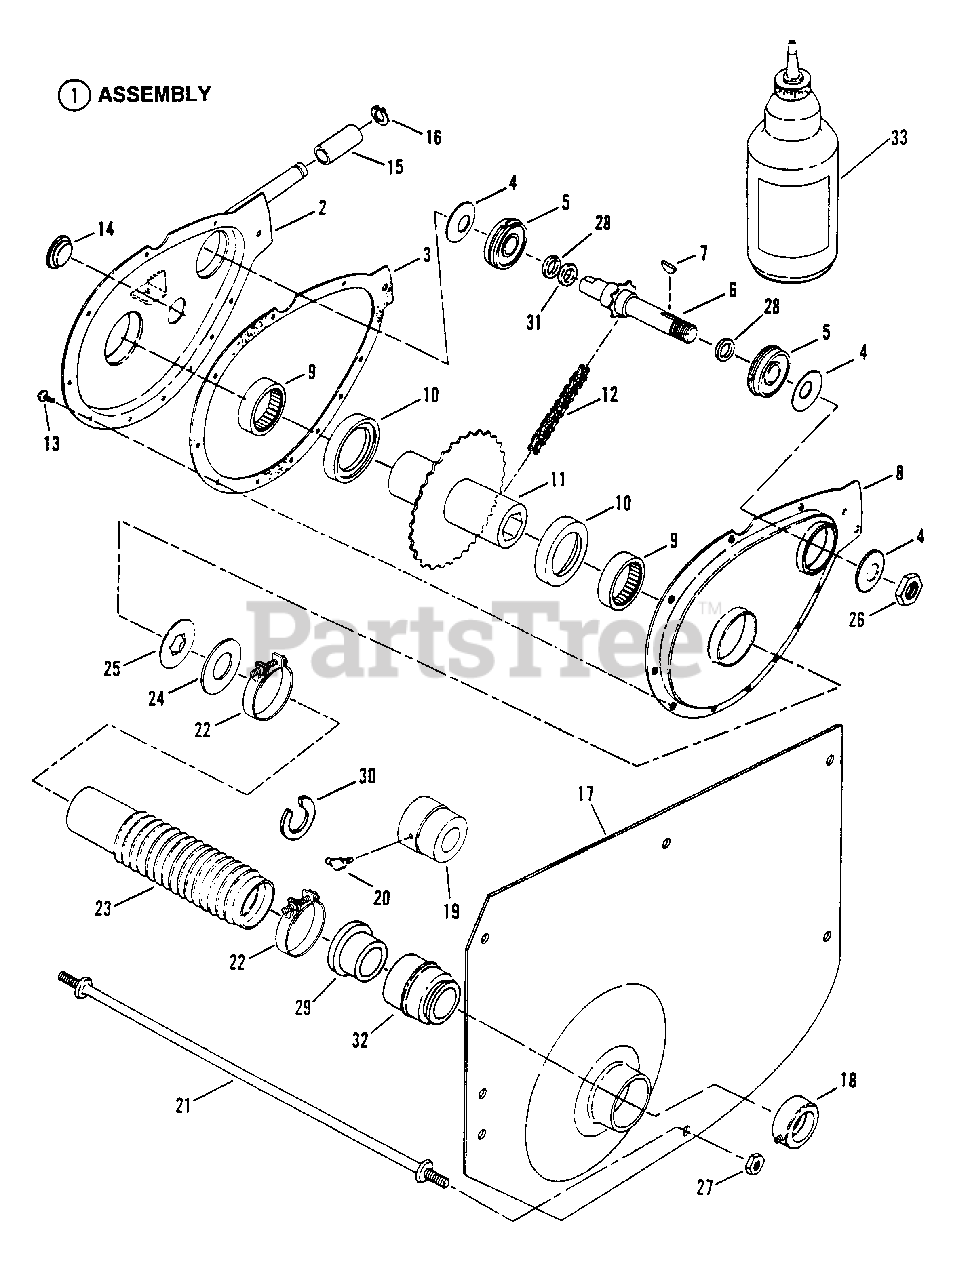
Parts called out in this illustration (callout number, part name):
1	ASSEMBLY, Chain Case
2	CASE, Sprocket
3	GASKET, Case Cover
4	WASHER, Belleville
5	BEARING, Ball
6	SPROCKET & SHAFT
7	KEY, 1/8 x 5/8" Woodruff
8	COVER, Chain Case
9	BEARING, Needle
10	WASHER, Nylon Thrust
11	HUB & SPROCKET
12	CHAIN
13	SCREW, #10-24 x 1/2" Hex Washer Self-Tap (Torx)
14	PLUG, Oil Fill & Check
15	ROLLER
16	RING, Retaining
17	FENDER, Left Hand
18	COLLAR, Lock
19	BEARING, Left Hand Fender
20	FITTING, Lube
21	ROD, Cross-Tie
22	CLAMP, Boot
23	BOOT, Oil Seal
24	WASHER, Thrust Nylon
25	WASHER, Thrust
26	NUT, 5/8-18 Hex Lock
27	NUT, 5/16-24 Hex Flange Lock
28	O-RING
29	SPACER
30	WASHER, Shim
31	WASHER, Shim
32	BEARING, Left Hand Fender
33	GREASE, Transmission
